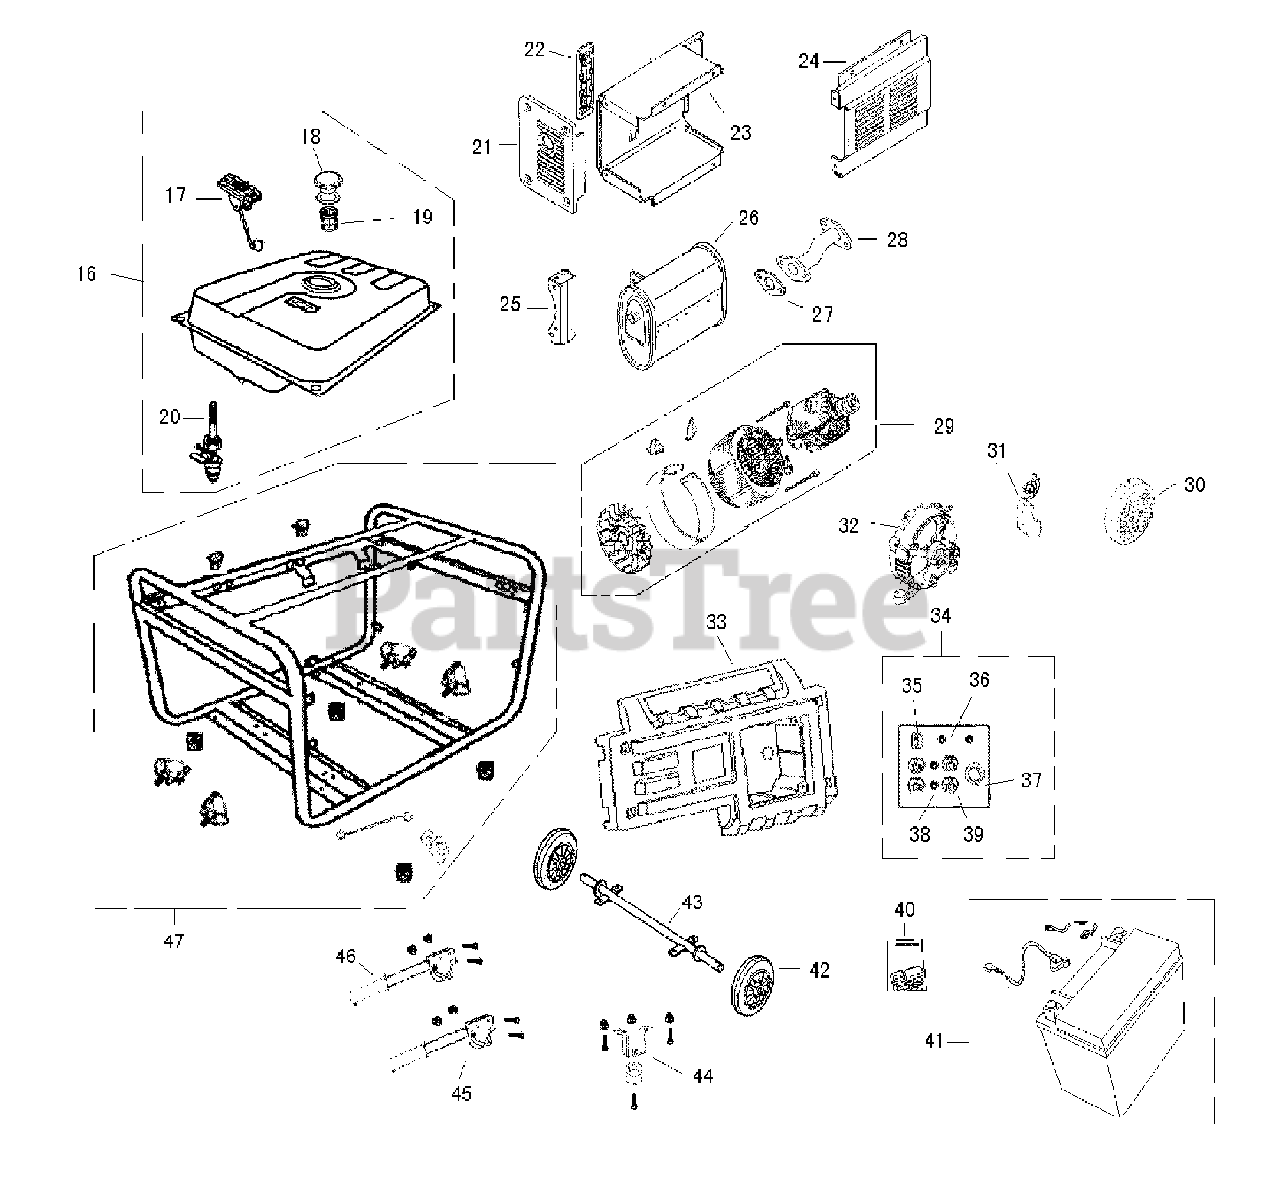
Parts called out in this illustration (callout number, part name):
16	TANK COMP., FUEL
17	METER COMP., FUEL
18	CAP COMP.,FUEL FILLER
19	FILTER, FUEL TANK
20	COCK COMP., FUEL
21	PROTECTOR, MUFFLER SIDE
22	SEAL, PROTECTOR MUFFLER
23	PROTECTOR COMP., MUFFLER
24	PROTECTOR COMP., MUFFLER
25	STAY, MUFFLER
26	MUFFLER ASSY.
27	GASKET,MUFFLER
28	PIPE, COMP., EX.
30	COVER GENERATOR END
31	AUTOMATIC VOLTAGE REGULATOR
33	CASE, CONTROL PANEL
34	CONTROL PANEL ASSY.
35	SWITCH ASSY., COMBINATION
36	CIRCUIT BREAKER
37	SOCKET,L14-30
39	CIRCUIT BREAKER
40	OPERATORS MANUAL
41	BATTERY ASSY.
43	SHAFT COUP., WHEEL
45	HANDLE ASSY. , R
46	HANDLE ASSY., L
